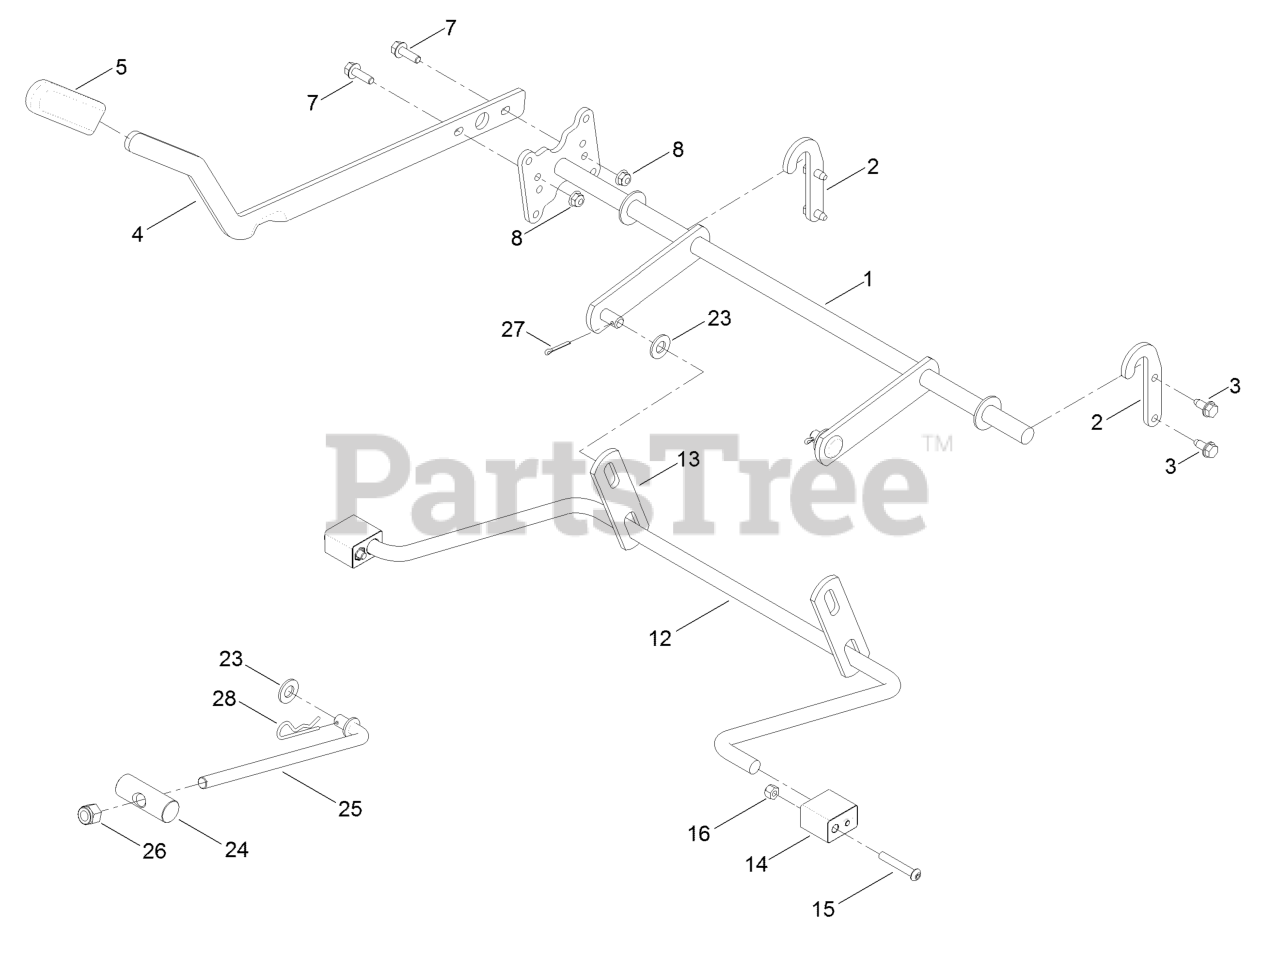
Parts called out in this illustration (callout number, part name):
1	LIFT-DECK, WIDE
2	BRACKET-LIFT
3	Screw-HWH 5/16-18 X 3/4 Tf
4	LEVER-LIFT
5	GRIP-LEVER
7	SCREW-HHF
8	NUT-HF, NI
12	ARM-LIFT, REAR (WIDE)
13	LINK-LIFT
14	BLOCK-PIVOT
15	SCREW-HSBH
16	NUT-LOCK, NI
23	WASHER-FLAT
24	PIN-PIVOT
25	ROD-MOUNT, DECK
26	NUT-HEX
27	PIN-COTTER
28	PIN-COTTER
